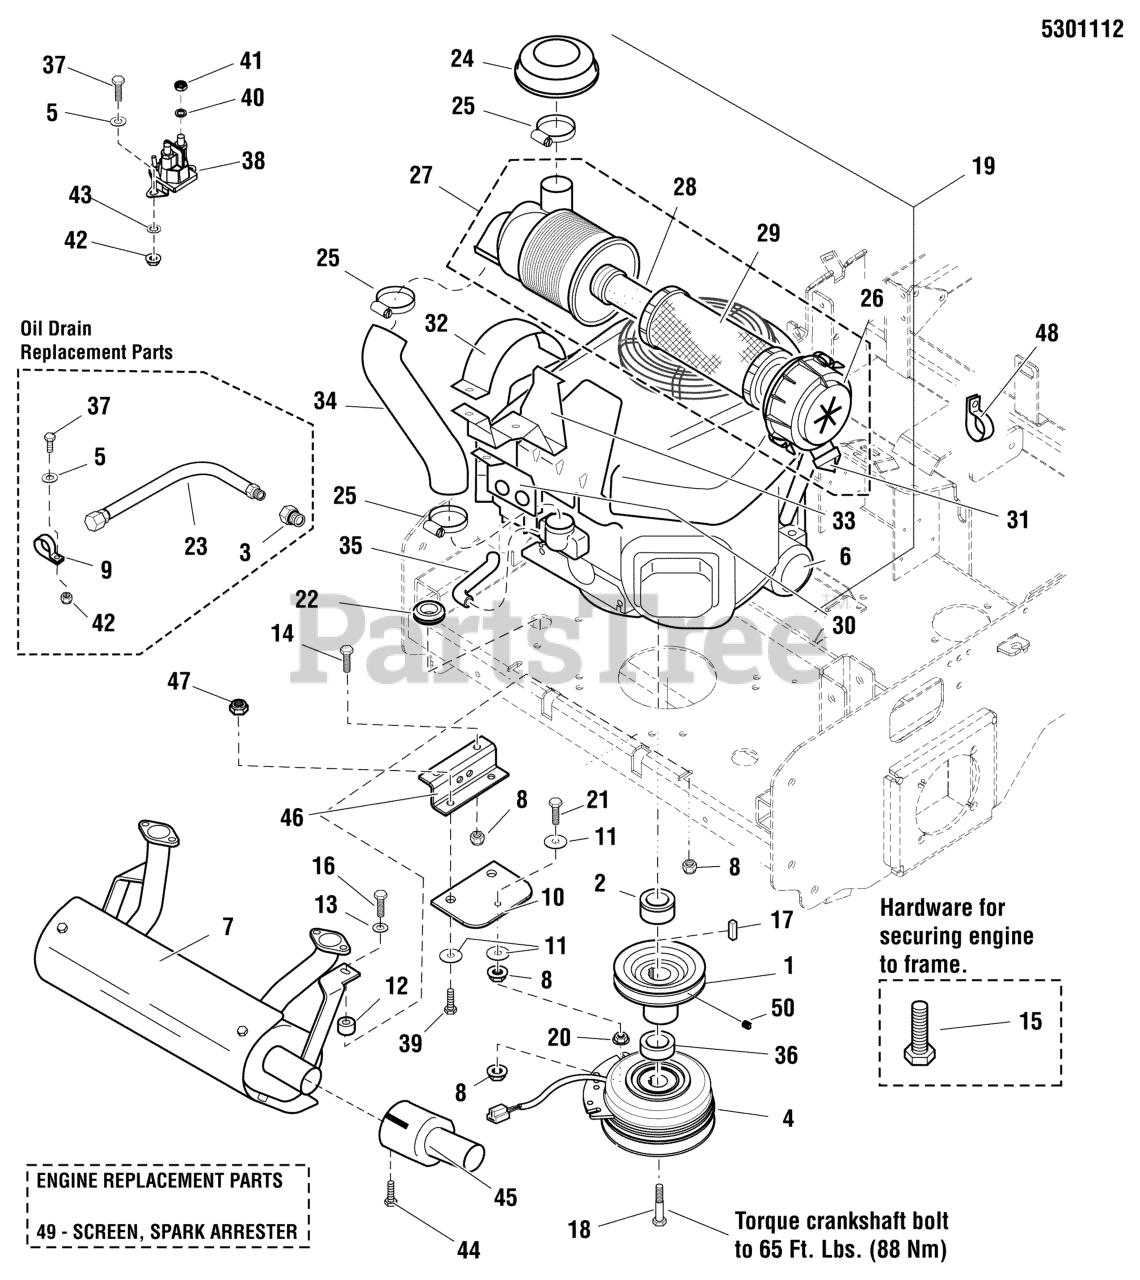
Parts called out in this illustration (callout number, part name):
1	PULLEY, 5.15 OD X 1-1/8 BORE B-SECT
2	SPACER, 1.13 X 1.75 X 1.03
3	ADAPTER, OIL DRAIN
4	* CLUTCH, 5218-134, WARNER
5	WASHER, 1/4 SAE
6	OIL FILTER (49065-2078) (SV)
7	MUFFLER, 27HP KAWASAKI, 5" CAN
8	NUT, 5/16-18 HEX NYLOCK FLANGE
9	CLAMP, VINYL INSULATED
10	CLUTCH ANCHOR PAD
11	WASHER, .34 X 1.25 X 10 GA
12	SPACER, .39 X 1.00 X .80
13	WASHER, 5/16" SAE
14	BOLT, 5/16-18 X 1 GD5 YZ
15	BOLT,HEX FLG, SER GD5 3/8-16X1-1/4,PATCH
16	BOLT, 5/16-18 X 1-3/4 GD5 YZ
17	KEY, 1/4 SQ X 1
18	BOLT, CRANKSHAFT, 7/16 X 2-1/4
19	* ENGINE, 27HP KAWASAKI
20	NUT, 5/16-18 HEX SERRATED FLANGE (LARGE)
21	BOLT, 5/16-18 X 2-1/4 TFL, GD5 YZ
22	GROMMET, 7/8
23	HOSE, OIL DRAIN
24	RAIN COVER
24	RAIN COVER, 27, 34 & 37
25	CLAMP, 27, 34 & 37
25	CLAMP
26	CAP END, FILTER CASE, 27, 34 & 37
26	FILTER CASE
27	AIR FILTER ASSEMBLY, 27, 34 & 37
27	AIR FILTER ASSEMBLY
28	AIR FILTER, SECONDARY, 27, 34 & 37
28	AIR FILTER, SECONDARY
29	AIR FILTER, PRIMARY, 27, 34 & 37
29	AIR FILTER, PRIMARY
30	BRACKET PLATE, SUPPORT, 27
31	RUBBER DUST VALVE, 27, 34 & 37
31	RUBBER DUST VALVE
32	BRACKET PLATE, UPPER, 27, 34 & 37
32	CASE BRACKET
33	BRACKET PLATE, LOWER, 27
33	CASE BRACKET
34	AIR INLET TUBE
34	AIR INLET TUBE, 27
35	BREATHER TUBE, 27
35	BREATHER TUBE
36	SPACER, 1.13 X 1.75 X .62
37	BOLT, 1/4-20 X 3/4 GD5 YZ
38	SOLENOID-4 POLE 12 VOLT DC (TROMBETTA)
39	BOLT, 3/8-16 X 1" GD5 CZ
40	WASHER, 5/16 LIGHT LOCK (SV)
41	NUT, 5/16-24 JAM (SV)
42	NUT, 1/4-20 HEX NYLOCK FLANGE
43	WASHER, 1/4 INTERNAL TOOTH LOCK
44	SCREW,SELF-TAP,#8-32 X 3/8,WASH HEX, CZ
45	EXTENSION, TAILPIPE, 3" - BLACK
46	ANCHOR, CLUTCH - BLK
47	NUT, 3/8-16 HEX NYLOCK FLANGE
48	CLAMP, HOSE, 1.000 DIA
50	SET SCREW, 5/16-18 X 3/8, KNURL, W/PATCH
